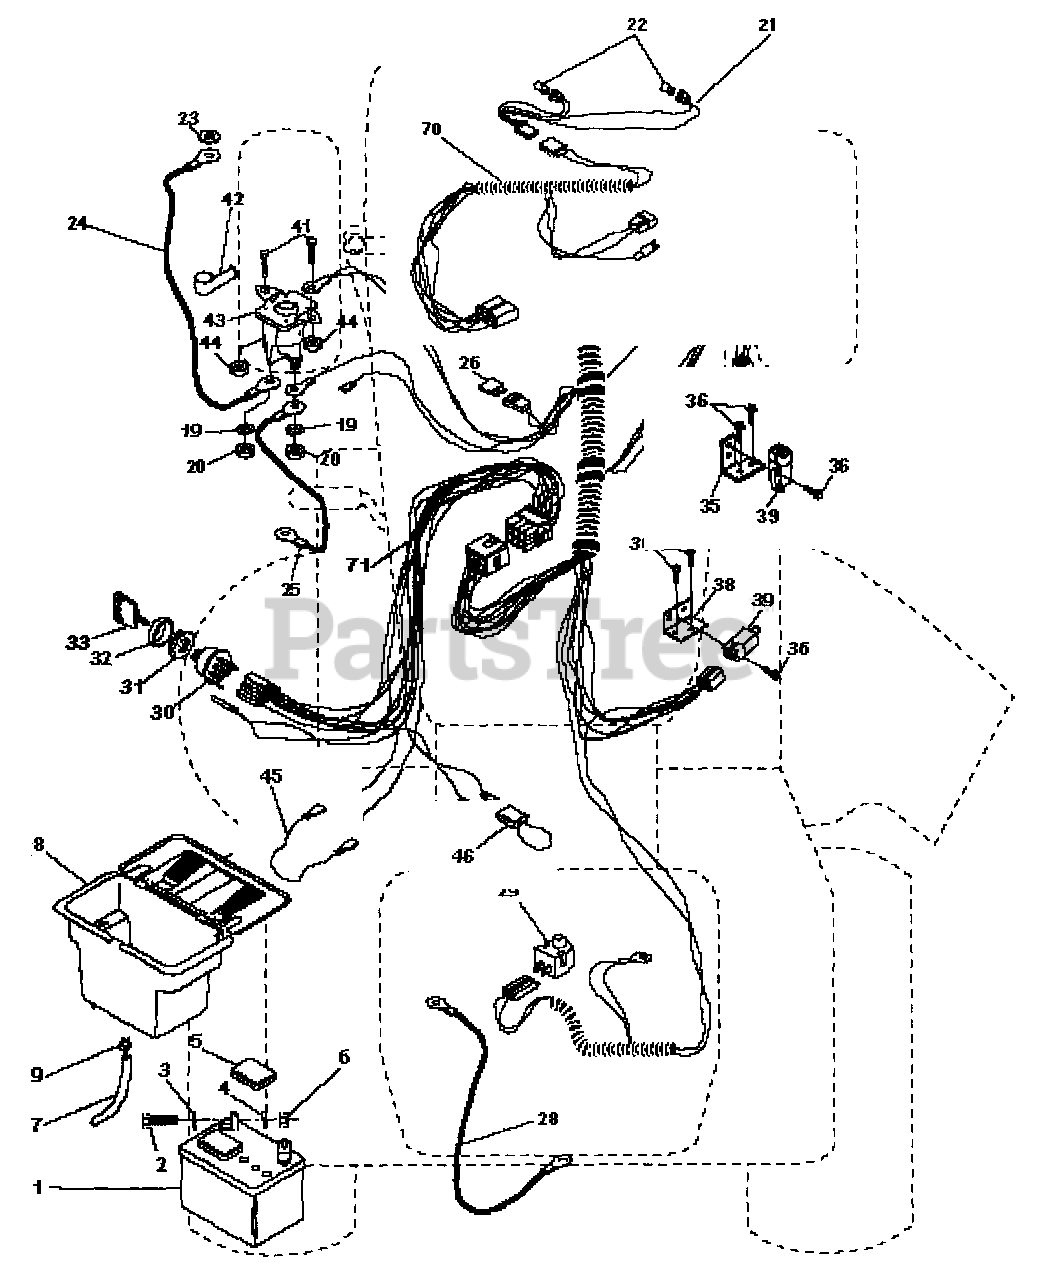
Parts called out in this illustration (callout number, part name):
1	Battery 12 Volt 25 Amp
2	Bolt Hex Hd 1/4-20unc X 3/4
3	Washer 9/32 X 5/8 X 16 Ga
4	Washer Lock Hvy Helical 1/4
5	Caps Battery 20/25/30 AMP
6	Nut Fin Hex 1/4-20 Unc
7	Tube Plastic 20"
8	Battery Case Hng Mech
9	Clamp Hose Olive
19	Washer Lock 1/4
20	Nut Jam Hex 1/4-20 Unc
21	Harness Asm Light W/4152j
22	Bulb Light #1156
23	Washer Lock Internal Tooth 1/4
24	Cable Battery 6 Ga 11" red
25	Cable Battery 6 Ga 43" red
26	Fuse 30 AMP Auto Green
28	Cable Ground 6 Ga 12" black
29	Switch Plunger Nc Gray
30	Switch Ign 4 Pos.
31	Nut Ignition
32	Cover Sw Key Blk 1 25 Text SLT
35	Bracket Switch Clutch
36	Screw Tap Hex #10-24unc X 1/2
38	Bracket Switch Interlock
39	Switch Intlk Clutch Gry 4 Term
40	Harness Ign Lt Mech Dash
41	Bolt Fin Hex 1/4-20 x 1/2
42	Cover Terminal Red
43	Solenoid
44	Nut Keps Hex 1/4-20 Unc
45	Adapter Ammeter rectangular
46	Protection Wire Loop (Hourmeter)
70	Harness Eng. B&S
71	Harness Dash Lt Private Label
